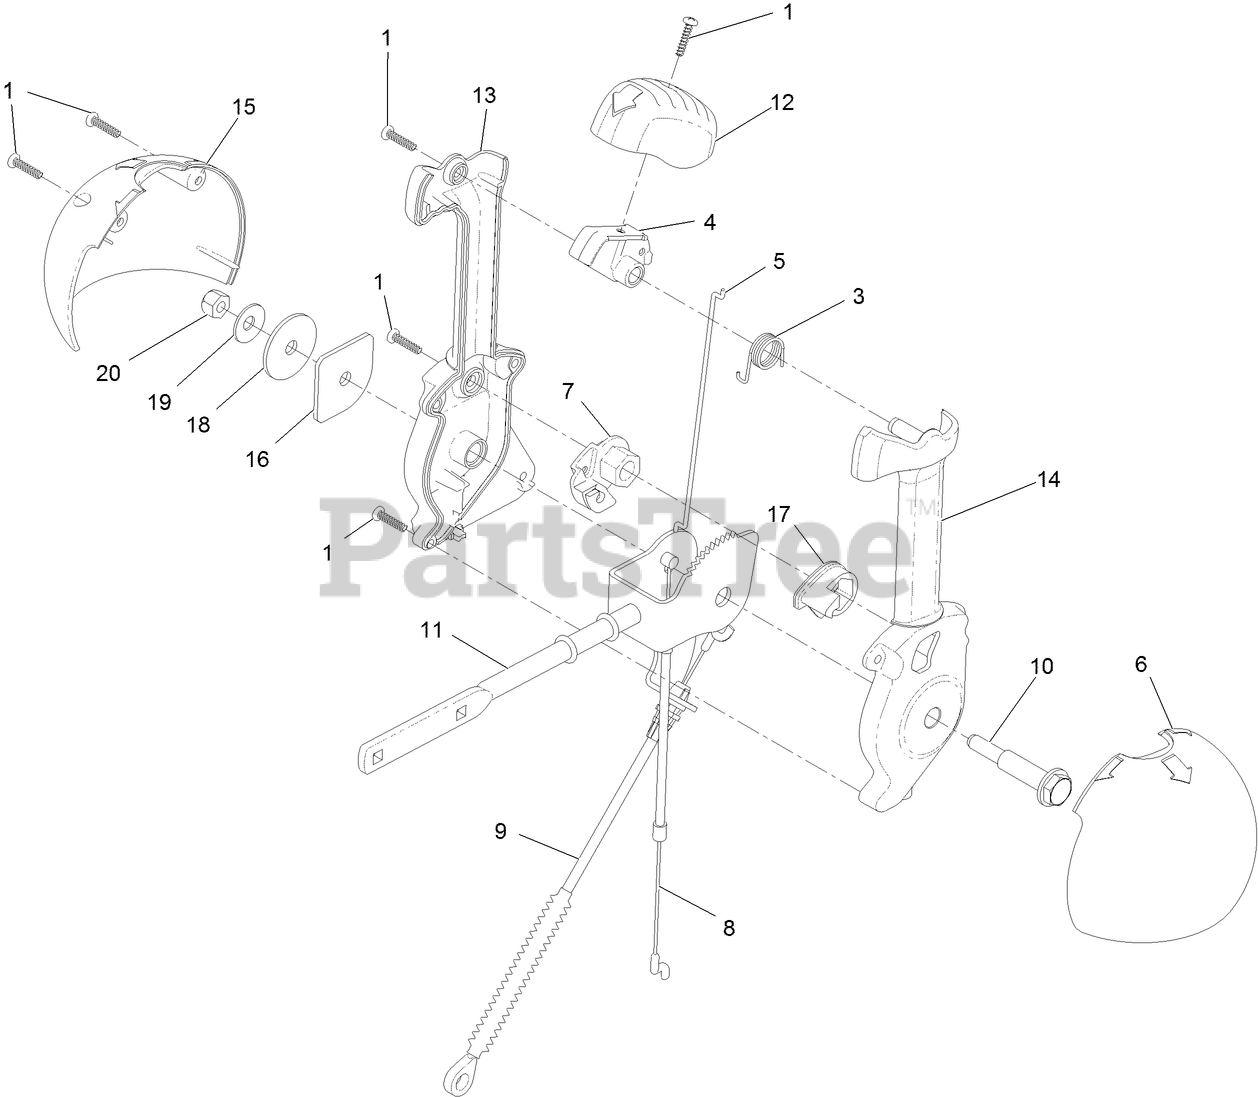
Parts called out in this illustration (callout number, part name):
1	SCREW-PPH
3	SPRING-TORSION
4	TRIGGER-LATCH
5	LINK-LATCH
6	COVER-LEVER, CHUTE (LH)
7	LEVER-CABLE, DEFLECTOR
8	CABLE-RELEASE, CHUTE
9	CABLE-CONTROL, DEFLECTOR
10	SCREW-SHOULDER
11	CHUTE CONTROL ROD
12	CAP-LEVER
13	LEVER-CONTROL, CHUTE (RH)
14	LEVER-CONTROL, CHUTE (LH)
15	COVER-LEVER, CHUTE (RH)
16	PLATE-FRICTION
17	PAWL-LATCH
18	WASHER-NYLON
19	WASHER-BELLEVILLE
20	NUT-HEX
